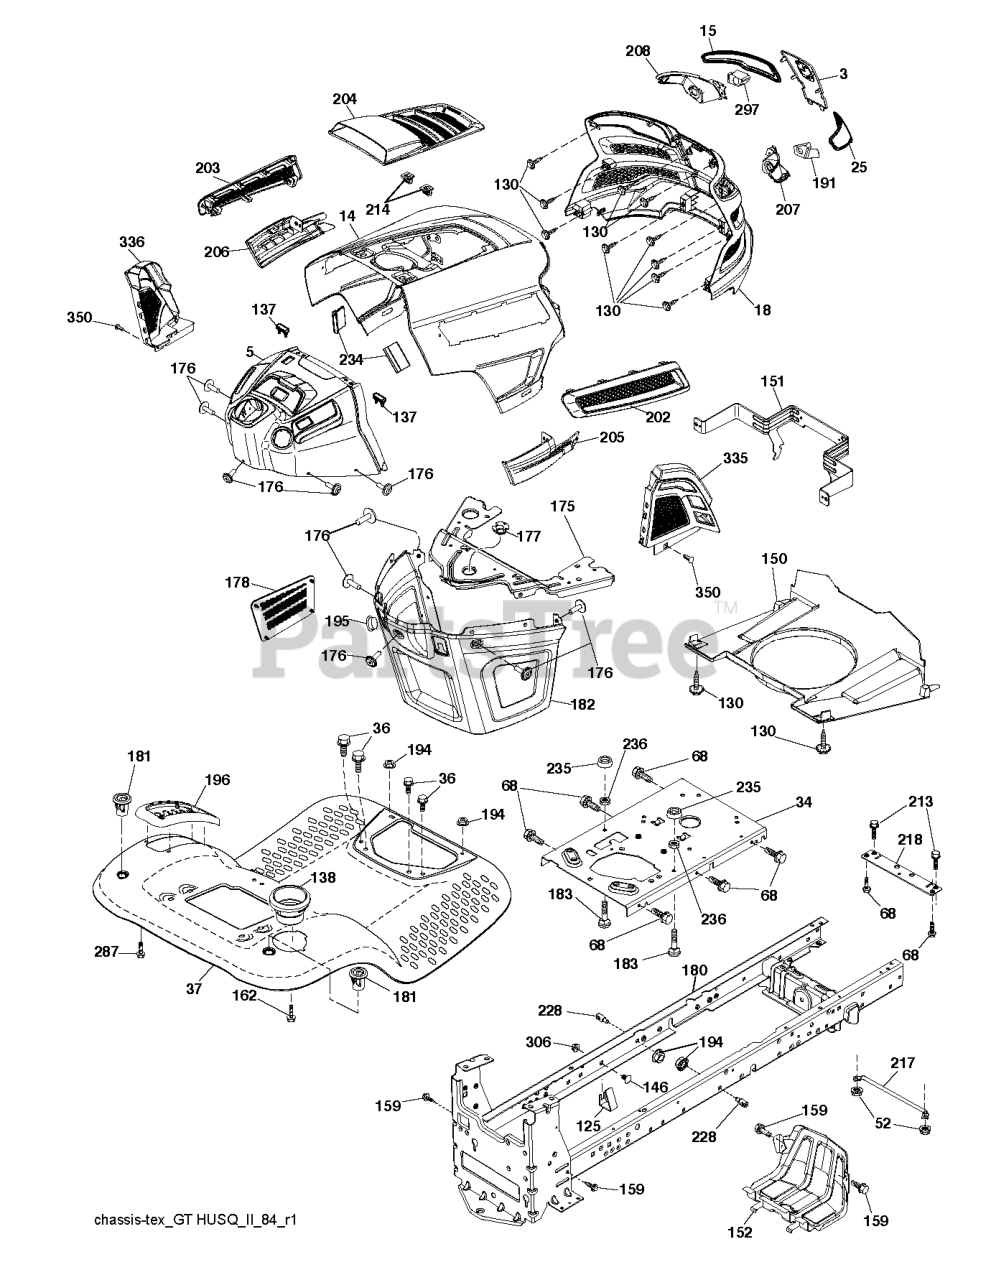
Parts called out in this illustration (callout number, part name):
3	APPLIQUE.SUBASM.GT.HUSQ.II
5	RP.DASH.UPP.GT2.SM.MC.CHOKE
14	HOOD.ASM.HUSQVARNA.GT.TEX.ORAN
15	LENS.HEADLIGHT.LH.GTII.2011
18	GRILLE.SUBSTRATE.2011.
25	LENS.HEADLIGHT.RH.GTII.2011
34	PLATE.ENGINE.WELDED.CHASSIS
36	SCREW 5/16"
37	FENDER.TLT.PDL.CNTRL.W/CPH.ORG
52	LOCKNUT
68	Screw 5/16-18 x 1/2 Hex, Self Tapping 5/16-18 x 1/2
125	CLIP.FUEL.LINE
130	SCREW.#10 X 0.750.BOS
137	BUMPER DASH
138	HOLDER.CUP.LT.GREY
146	BOLT.RDHD.SHT.SQNK.3/8-16X5/8
150	AIR DUCT.GTV2(1.66"RING HEIGHT
151	BRACKET.PIVOT.HOOD.GT.HUSQ.II
152	SHIELD.BROWNING.PNT.GT.V2
159	SCREW, 3/8-16X3/4
162	SCREW.HI-LO.CONSOLE
175	PLATE.CROSSMEMBER.HUSQ
176	SCREW.#10-24X5/8.RN.QU
177	BUSHING, STEERING
178	CARGO.ASM.NET.TXGT.W/C
180	CHASSIS
181	BUSHING.MNT.FEND.CRGO.TEX.49
182	DASH.LOWER.COMMON.12V.ADAPTOR
183	BOLT.5/16-18X1-1/4 FULL THD
191	INSERT.REFLECTIVE.RH.HUSQ.GTII
194	NUT LOCK HEX FLANGE 5/16-18
195	PLUG.HOLE.DASH.LOWER.12V.BLK
196	DECKLFT.CONSOL FULL ASSM GREY
202	VENT.SIDE.RH.GT.HUSQ.II.
203	VENT.SIDE.LH.GT.HUSQ.II.498
204	VENT.TOP.HUSQ.GT2
205	SIDE.TRIM.RH.GT.HUSQ.II
206	SIDE.TRIM.LH.GT.HUSQ.II.GRAY
207	BEZEL LIGHT.RH.GT.II.MYLAR
208	BEZEL LIGHT.LH.GT.II.MYLAR
213	BOLT
214	CLIP.RETAINER.TINNER.
217	ROD.PIVOT.HOOD
218	X-PIECE.HOOD.STOP.NON/
228	STUD.FASTNER.W/ANTI-ROTATE
234	BUMPER.HOOD.TEX.HUSQVARNA
235	SPACER FENDER
236	NUT.CENTERLOCK.5/16-
287	SCREW 1/4X20
297	INSERT.REFLECTIVE.LH.HUSQ.GTII
306	NUT LOCK FLG 3/8-16 UNC
335	COVER.LOWER.DASH.RH.BLACK
336	COVER-LH.LOWER.DASH.GT2.BLACK
350	CLIP.X-MAS.TREE
